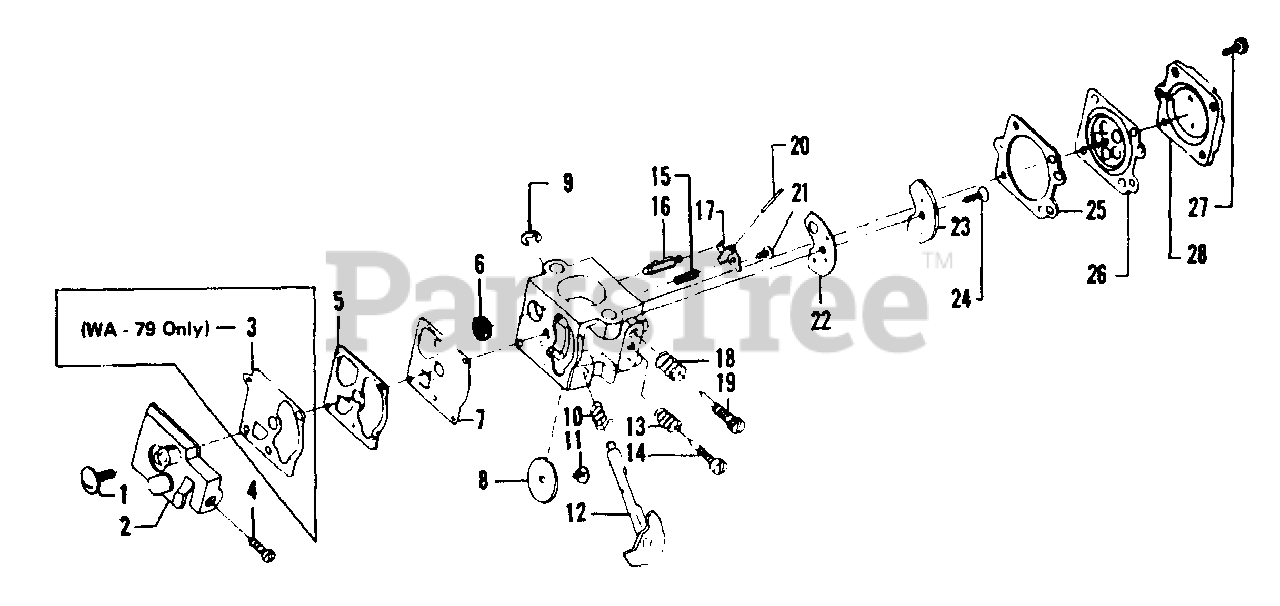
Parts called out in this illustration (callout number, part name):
1	Screw - Pump Cover
2	Pump Cover Ass'y WA-79 (# 35148)
2	Pump Cover Ass'y WA-149 (# 35183)
3	Diaphragm - Pump (WA-79 - # 35148 Only)
4	Screw -Idle Adjustment
5	Gasket - Pump WA-79 (# 35148)
5	Gasket - Pump WA-149 (# 35183)
6	Screen -Inlet
7	Diaphragm - Pump WA-79 (# 35148)
7	Diaphragm - Pump WA-149 (# 35183)
8	Valve - Throttle
9	Clip - Throttle Shaft
10	Spring - Throttle Return
11	Screw - Throttle Valve
12	Shaft Assembly - Throttle
13	Spring - Idle Needle
14	Needle - Idle
15	Spring -Metering Lever
16	Valve - Inlet Needle
17	Lever - Metering
18	Spring - Hi Speed Needle
19	Needle - Hi Speed
20	Pin - Metering Lever
21	Screw - Metering Lever Pin
22	Gasket - Circuit Plate
23	Plate - Circuit
24	Screw - Circuit Plate
25	Gasket - Metering Diaphragm
26	Diaphragm Assembly - Metering
27	Screw - Assembly - Metering Cover & Throttle Shaft Clip
28	Cover - Metering Diaphragm
